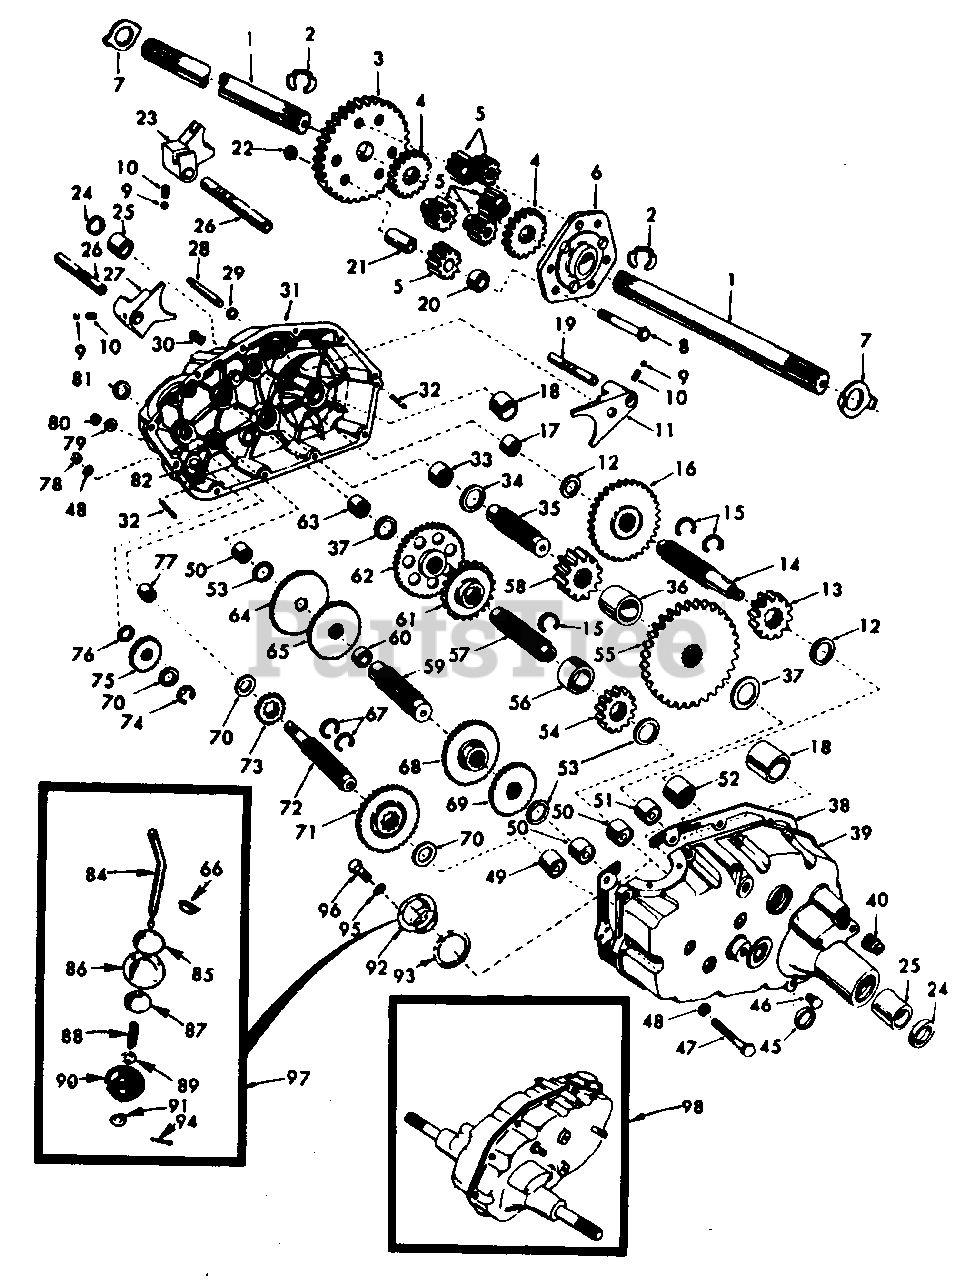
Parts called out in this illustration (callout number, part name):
1	Axle Shaft (AYP part number)
2	Retaining Ring (AYP part number)
3	Final Drive Gear (AYP part number)
4	Differential Gear (AYP part number)
5	Differential Pinion (AYP part number)
6	Differential Carrier (AYP part number)
7	Axle Thrust Washer (AYP part number)
8	Hex Bolt (AYP part number)
9	Steel Ball (AYP part number)
10	Spring Shift Fork Detent (AYP part number)
11	Shift Fork, High-Low Range (AYP part number)
12	Thrust Bearing Race (AYP part number)
13	4th Reduction Pinion (AYP part number)
14	3rd Reduction Gear Shaft (AYP part number)
15	Snap Ring-Crescent Type (AYP part number)
16	High-Low Range Gears (AYP part number)
17	Needle Bearing (AYP part number)
18	Sintered Iron Bearing (AYP part number)
19	Shift Fork Shaft High-Low Range (AYP part number)
20	Differential Pinion Spacer (AYP part number)
21	Differential Pinion Spacer (AYP part number)
22	Gripco Centerlock Nut (AYP part number)
23	L.H. Shift Fork (AYP part number)
24	Oil Seal (AYP part number)
25	Sintered Iron Bearing (AYP part number)
26	Shift Fork Shaft (AYP part number)
27	R.H. Shift Fork (AYP part number)
28	Shift Shaft, High-Low Range (AYP part number)
29	Oil Seal (AYP part number)
30	Pressure Relief Valve (AYP part number)
31	R.H Gearcase Rvs Idler Shaft & Bearings (Inc. 17,18,25,33,50,63,76,77 & 82) (AYP part number)
32	Dowel Pin (AYP part number)
33	Needle Bearing (AYP part number)
34	Thrust Bearing Race (AYP part number)
35	4th Reduction Gear Shaft (AYP part number)
36	4th Reduction Gear Spacer (AYP part number)
37	Thrust Bearing Race (AYP part number)
38	Gearcase Gasket (AYP part number)
39	L.H. Gearcase and Bearings (Inc. 18,25,49, 50 (2), 51 and 52) (AYP part number)
40	N.P.T. Pipe Plug (AYP part number)
45	Oil Seal (AYP part number)
46	N.P.T. Pipe Plug (AYP part number)
47	Hex Bolt 5/16-18 x 1-1/2 Grade 5 (AYP part number)
48	Lockwasher (AYP part number)
49	Needle Bearing (AYP part number)
50	Needle Bearing (AYP part number)
51	Needle Bearing (AYP part number)
52	Needle Bearing (AYP part number)
53	Thrust Bearing Race (AYP part number)
54	3rd Reduction Pinion-Low (AYP part number)
55	4th Reduction Gear (AYP part number)
56	3rd Reduction Pinion Spacer (AYP part number)
57	2nd Reduction Gear Shaft (AYP part number)
58	Final Dive Pinion (AYP part number)
59	1st Reduction Gear Shaft
60	1st Reduction Shaft Spacer (AYP part number)
61	3rd Reduction Pinion High (AYP part number)
62	2nd Reduction Gear (AYP part number)
63	Needle Bearing (AYP part number)
64	Low Speed Gear and 2nd Reduction Pinion Cluster (AYP part number)
65	Reverse Gear (AYP part number)
66	Key-Hi-Pro (AYP part number)
67	Snap Ring Crescent Type (AYP part number)
68	Intermediate Speed Gear (AYP part number)
69	High Speed Gear (AYP part number)
70	Thrust Bearing Race (AYP part number)
71	Intermediate and High Speed Cluster Pinions (AYP part number)
72	Input Shaft (AYP part number)
73	Low Speed Pinion (AYP part number)
74	E-Ring (AYP part number)
75	Reverse Idler Gear (AYP part number)
76	Reverse Idler Thrust Washer (AYP part number)
77	Needle Bearing (AYP part number)
78	Hex Nut 5/16-18 (AYP part number)
79	Sealing Washer (AYP part number)
80	Hex Jam Nut (AYP part number)
81	Oil Seal (AYP part number)
82	Reverse Idler Shaft (AYP part number)
84	Bent Gear Shift Lever (AYP part number)
85	Gear Shift Cap (AYP part number)
86	Gear Shift Ball Cover and Pin (AYP part number)
87	Shift Lever Guide Ball - Keyed (AYP part number)
88	Spring (AYP part number)
89	Washer (AYP part number)
90	Shift Mechanism Seal (AYP part number)
91	Washer (AYP part number)
92	Gear Shift Gate and Reinforcement (AYP part number)
93	Shift Ball Cover Gasket (AYP part number)
94	Cotter Pin (AYP part number)
95	Lockwasher 5/16 (AYP part number)
96	Hex Bolt 5/16 x 18 UNC x 7/8 (AYP part number)
97	Gear Shift Lever Assy. (AYP part number)
98	Transaxle Assembly Less Brake Drum and Shift Lever (AYP part number)
